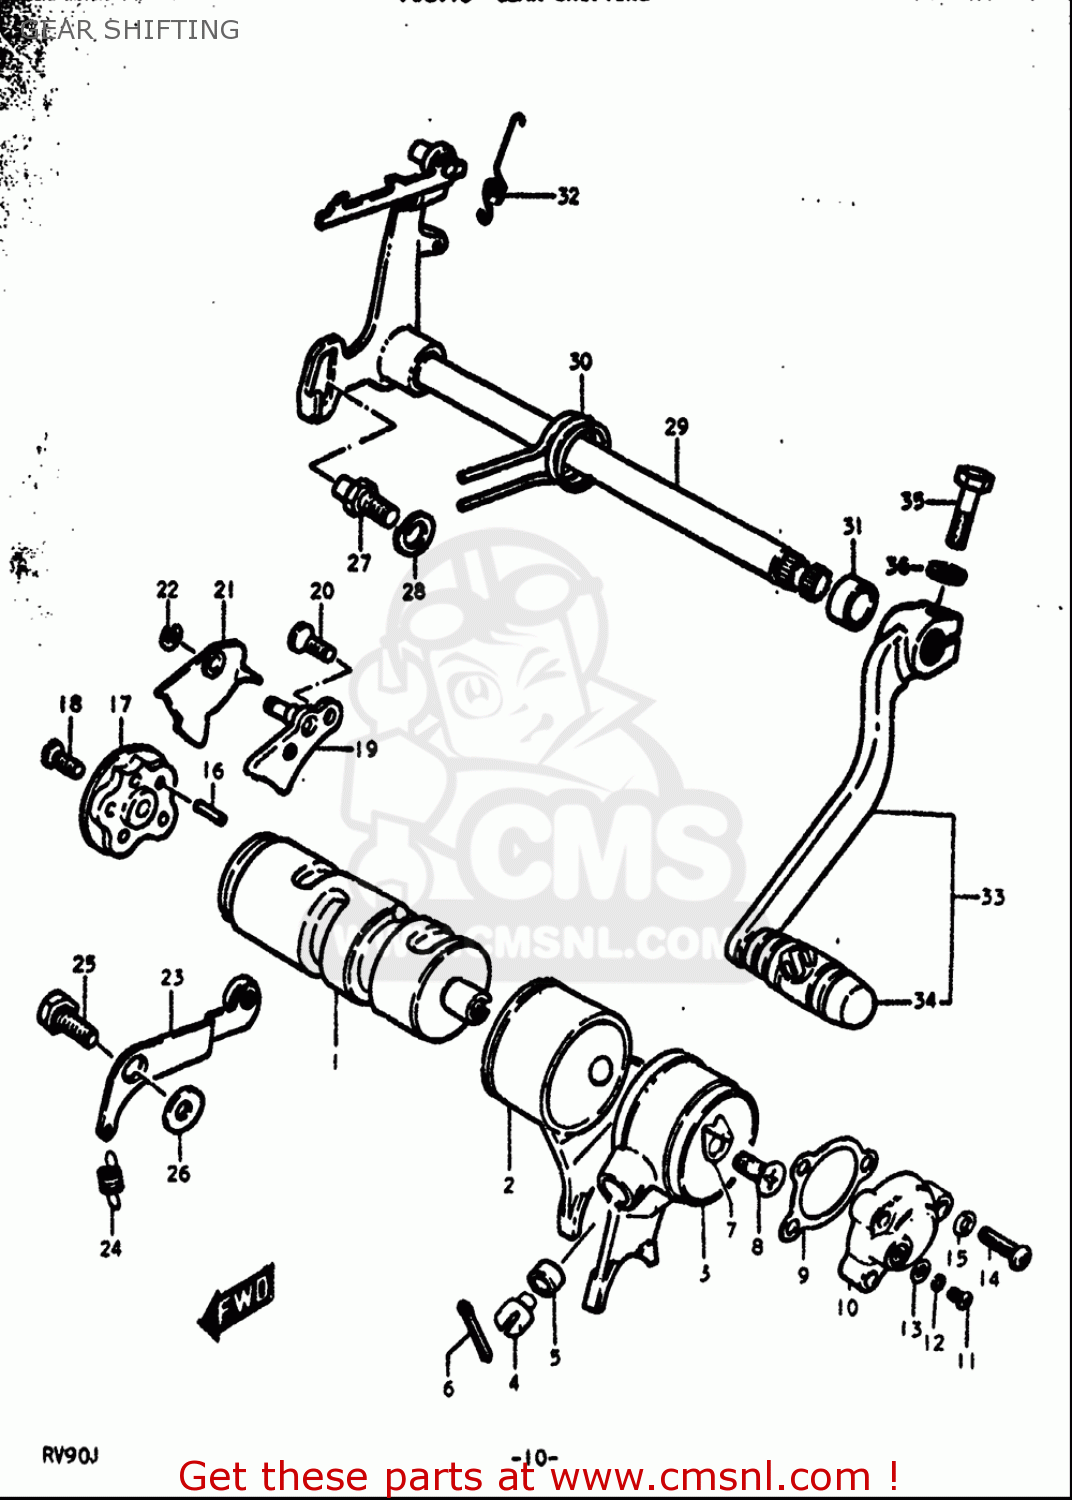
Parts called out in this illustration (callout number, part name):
3	FORK,GEAR SHIFT NO.2
5	SPACER(6X9.8X6)
6	PIN
7	CONTACT,GEAR SHIFT SWITCH
8	SCREW
9	GASKET,GEAR SHIFT SWITCH (NAS)
10	BODY,CHANGE SWITCH
11	SCREW
12	WASHER,LOCK
13	WASHER
14	SCREW
15	WASHER
16	PIN(4X20)
18	SCREW
20	SCREW
22	E RING
25	BOLT(6X16.1)
26	WASHER(6.5X16X3.2)
28	WASHER,LOCK
29	SHAFT,GEAR SHIFT
30	SPRING
31	SEAL,OIL (12X22X9)
32	SPRING
33	LEVER ASSY,GEAR SHIFT
34	RUBBER,GEAR SHIFT PEDAL
35	BOLT
36	WASHER,LOCK
